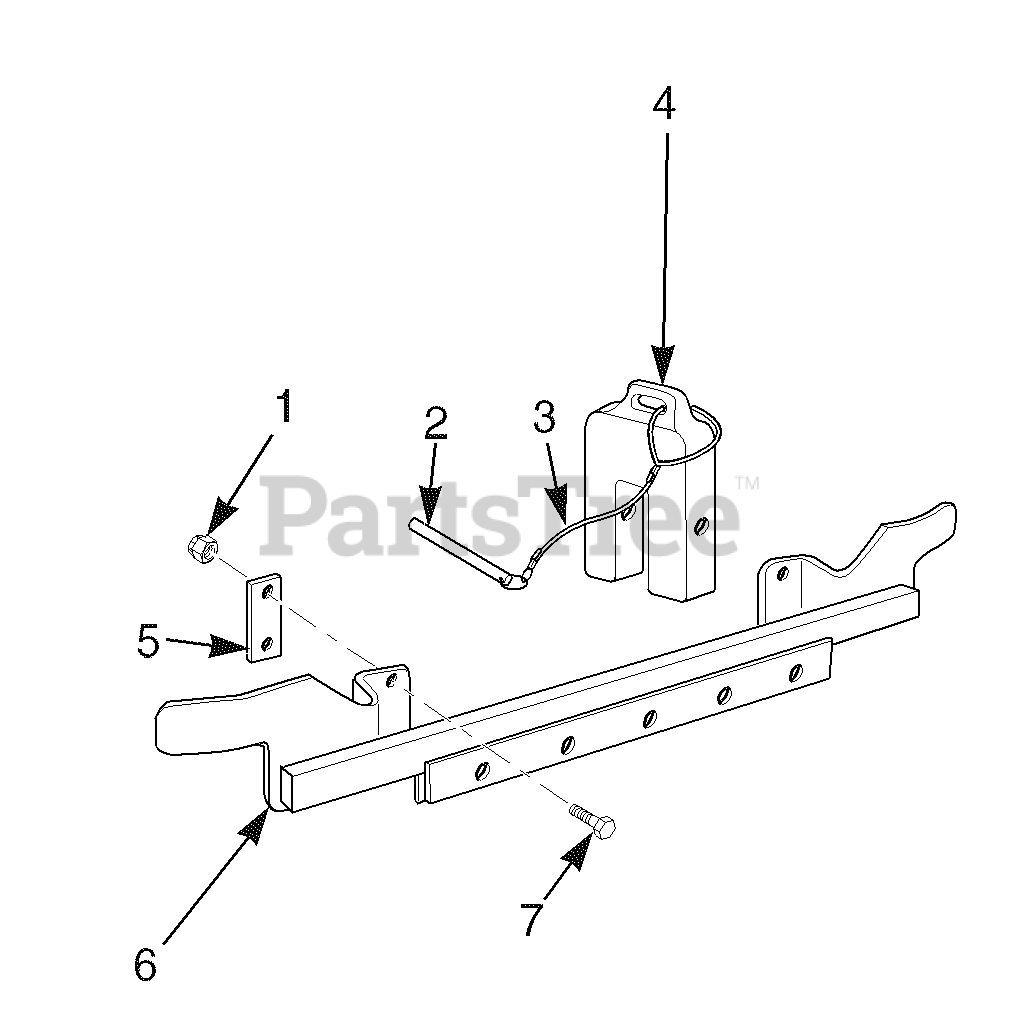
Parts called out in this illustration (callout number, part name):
1	Nut, Elastic Stop 3/8-16
2	Pin, 1/2 x 6-1/4"
3	Lanyard, Weight Pin
4	Weight Assembly
5	Clamp, Bar
6	Support Weldment, Front Weights
7	Bolt, Hex Head 3/8-16 x 1-1/2"
